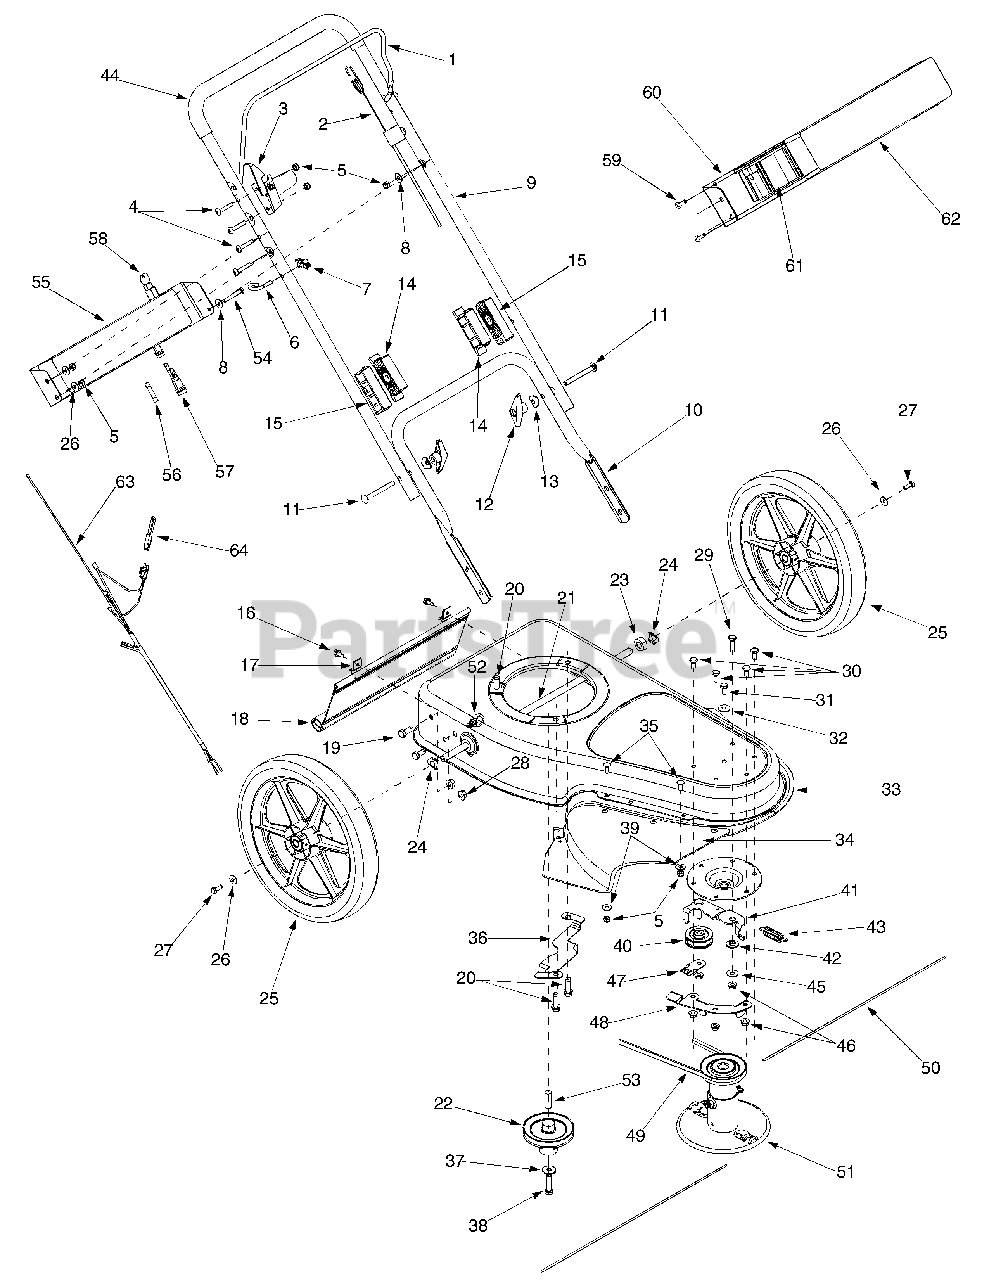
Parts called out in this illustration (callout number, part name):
2	Engagement Cable
3	Control Lock Bracket
4	Machine Screw 1/4-20 x 1.50
5	Hex Lock Nut 1/4-20
6	Eye Bolt 1/4-20
8	Flat Washer 260 ID x .270 OD
13	Shoulder Washer .320 ID x .93 OD
14	Lower Handle Connector
15	Upper Handle Connector
16	Hex Washer Screw 1/4-14 x .625
17	Trail Shield Clip
18	Trail Shield
19	Hex Cap Screw 3/8-16 x .750
20	Hex Washer Screw 3/8-16 x 1.25
21	Trimmer Axle
22	Flywheel Pulley
23	Spacer .51 ID x 1.0 OD
24	Spacer Washer .501 ID x 1.0 OD
25	Wheel Assembly
26	Bell Washer .265 ID x .75 OD
27	Hex Cap Screw 1/4-20 x .75
28	Flange Lock Nut 3/8-16
29	Screw 5/16-18 x 1.25
30	Screw 5/16-18 x .75
31	Hex Cap Screw 5/16-24 x .625
32	Bell Washer .325 ID x .930 OD
35	Hex Carriage Screw 1/4-20 x .75
38	Hex Cap Screw 3/8-24 x 1.50
39	Flat Washer .28 ID x .74 OD
40	Idler Pulley
41	Idler Bracket Assembly
42	Idler Spacer
43	Extension Spring .50 Dia x 1.88 Lg
44	Handle Grip
45	Flat Washer
46	Flange Lock Nut 5/16-18
49	V-Belt
50	Trimmer Line .155 Dia
51	Spindle Assembly
52	Cable Retainer Clip
54	Hex Cap Screw 1/4-20 x 1.75
55	Electric Starter
56	Fuse 7.5 amp
57	Fuse Holder
58	Key Switch
59	Screw #12-16 x 1.0
62	Upper Battery Tray
63	Wire Harness
64	Plug
